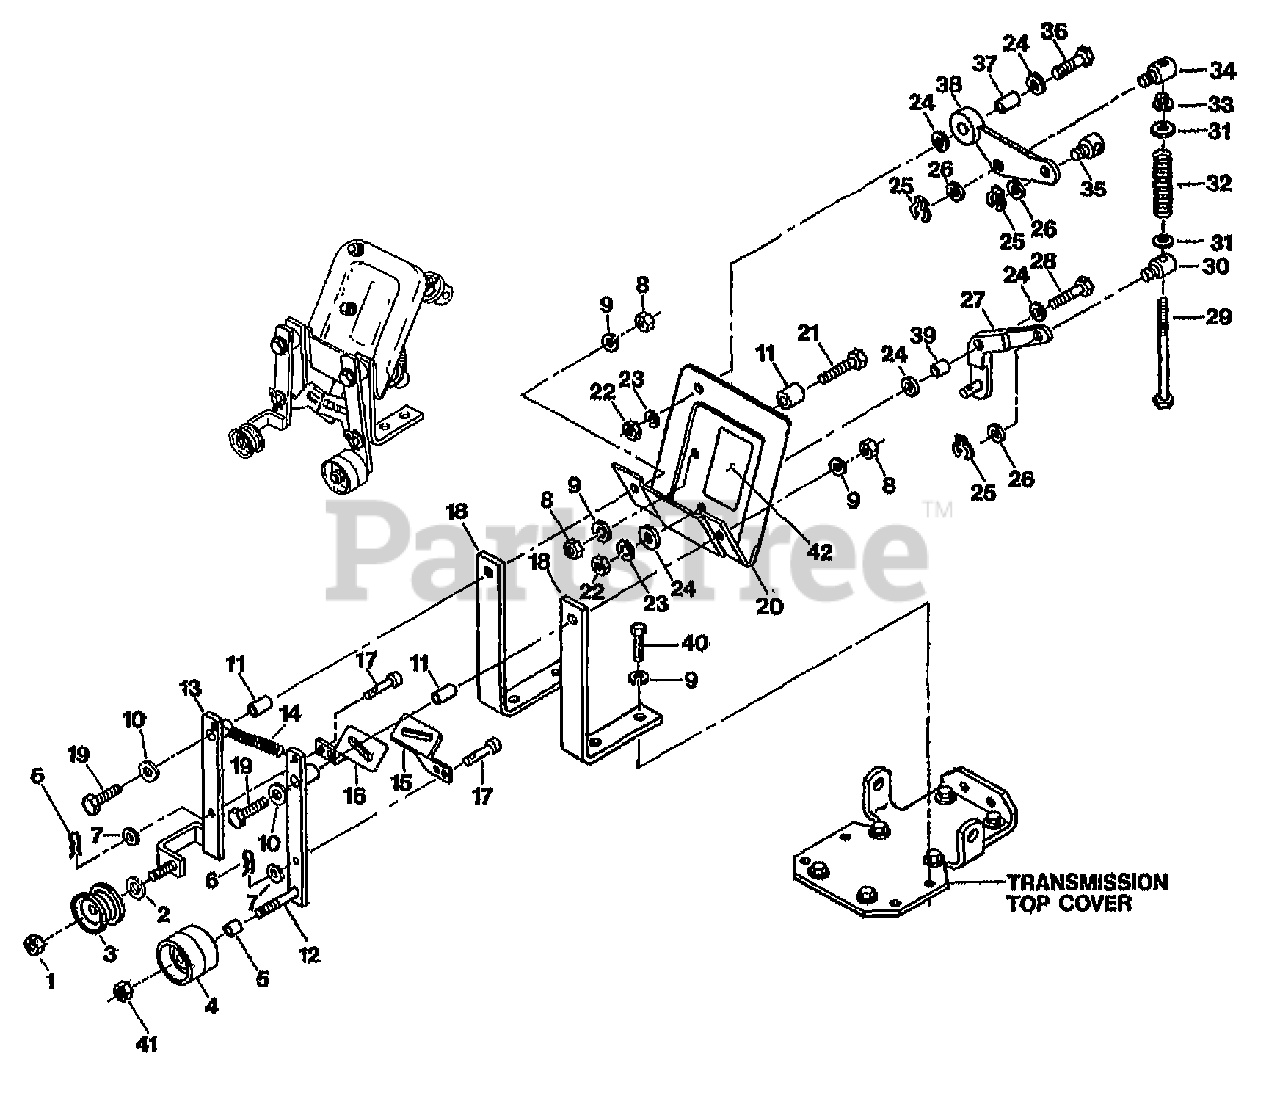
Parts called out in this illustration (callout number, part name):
1	NUT-LOCK 3/8-16 NYLON ZP
2	BUSHING-.54X.38X.08 (Reverse Idler Pulley)
3	IDLER-REV (Reverse Tiller Direction)
4	PULLEY-IDLER FORWARD (Forward Tiller Direction)
5	SPACER-IDLER FWD
6	PIN-CLIP .08
7	WASHER-FLAT 1/4 SAE
8	NUT-HEX 5/16-18 ZP
9	WASHER-LK .312 ZP
10	WASHER-#.75X.32X.09 ZP
11	BUSHING-.438X.323X.712
12	ARM-IDLER FWD PNT (LT, tiller direction.)
13	IDLER-REV (RT, tiller direction.)
14	SPRING-.436 X 3.25
15	LINK-FWD
17	PIN-CLEVIS .375X.719 ZP
18	MOUNT BAR-PNT (20691)
19	BOLT-HH 5/16-18 X 2 G5 ZP
20	BASE-SHIFTING W/DECAL (Inc. 42)
21	SCR-HH 5/16-18X1.25 G5ZP
22	NUT-HEX 3/8-16 ZP
23	WASHER-LK .375 @ DEPL
24	SPACER-.88X.385X.09 ZP
25	RING-KLIP .500 ZINC
26	WASHER-#.88X.51X.063 ZP (Pivot)
27	BELLCRANK-WELDMENT
28	SCR-HH 3/8-16X1.25
29	SCR-HH 1/4-20X4.5 G5
30	PIVOT-SLIDE
31	WASHER (Between lower pivot & spring, & between spring & retaining ring.)
32	SPRING-.52 X 3
33	RING-KLIP 5304-25
34	PIVOT-THREADED (Upper)
35	PIVOT-ROD (Forward/Neutral/Reverse Lever.)
36	BOLT-HH 3/8-16X1.5 FTH ZP
37	BUSHING-.5X.38X.665
38	RODCRANK
39	BUSHING-.5X.38X.4 (Bellcrank)
40	SCR-HH 5/16-18X1.0 G5 ZP
41	NUT-H/LK 3/8-16
42	DECAL-BELT WARNING
